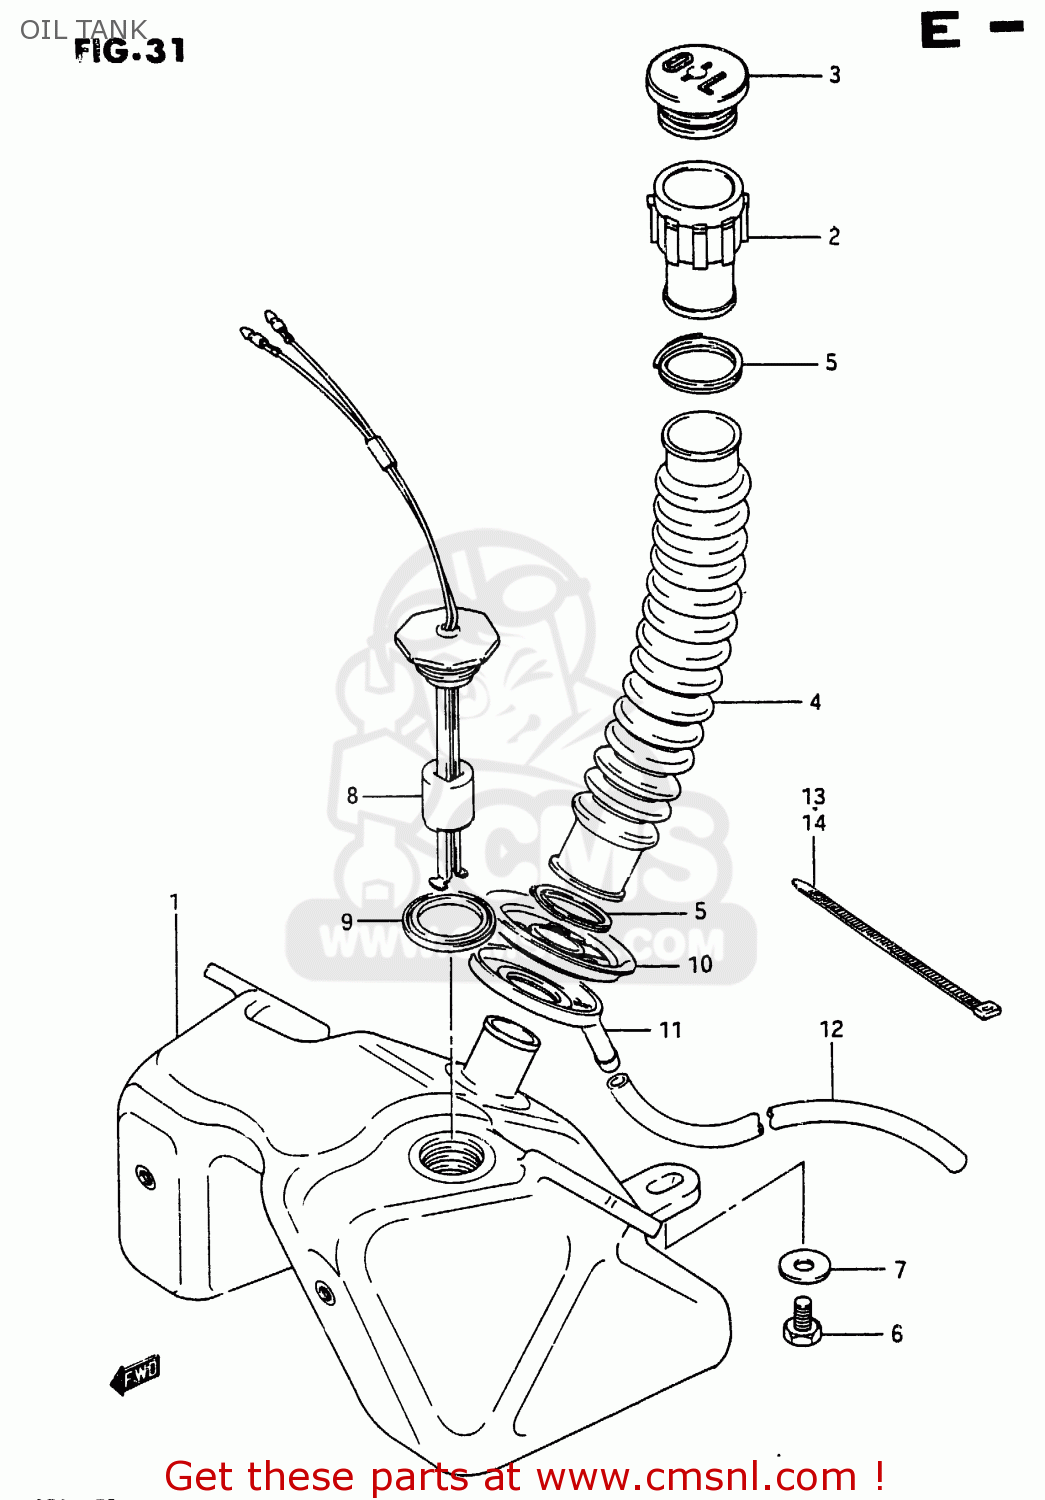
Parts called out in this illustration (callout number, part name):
1	TANK, OIL
2	INLET, OIL TANK
3	CAP,OIL TANK
4	HOSE, OIL TANK
5	CLIP
6	BOLT
7	WASHER
8	SWITCH,OIL LVL
9	GASKET (NAS)
10	RUBBER, OIL TANK
11	TRAY, FUEL/OIL DRAIN
12	HOSE,FUEL
13	CLAMP
14	CLAMP(L:187)
